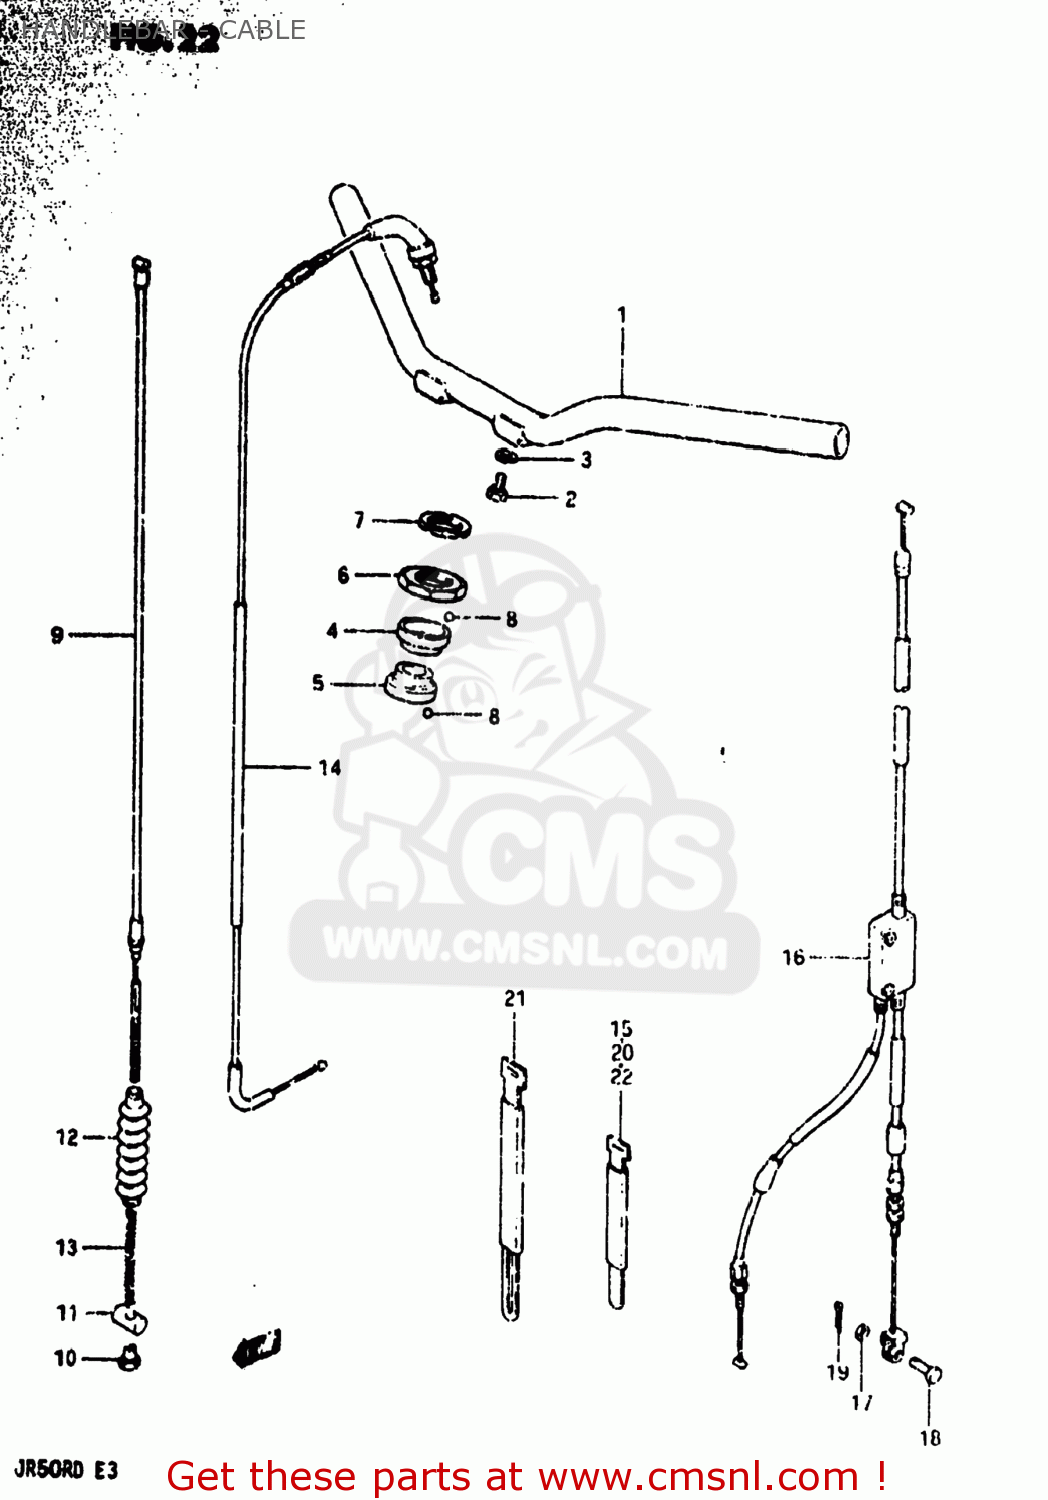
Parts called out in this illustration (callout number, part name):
1	HANDLEBAR
2	BOLT
3	LOCK WASHER
4	RACE,STEERING,INNER,UPPER
5	RACE,STEERING,INNER,LOWER
6	RACE,STEERING,OUTER,UPPER
7	NUT,STEERING STEM
8	BALL
9	CABLE ASSEMBLY,FRONT BRAKE
10	NUT
11	PIN,10X19
12	SEAL,DUST(7X16X75)
13	SPRING
14	CABLE ASSEMBLY,THROTTLE
15	CLAMP
16	CABLE ASSEMBLY,REAR BRAKE
17	WASHER
18	PIN(L:13)
19	PIN
20	CLAMP(L:250)
21	CLAMP L:110
22	CLAMP
